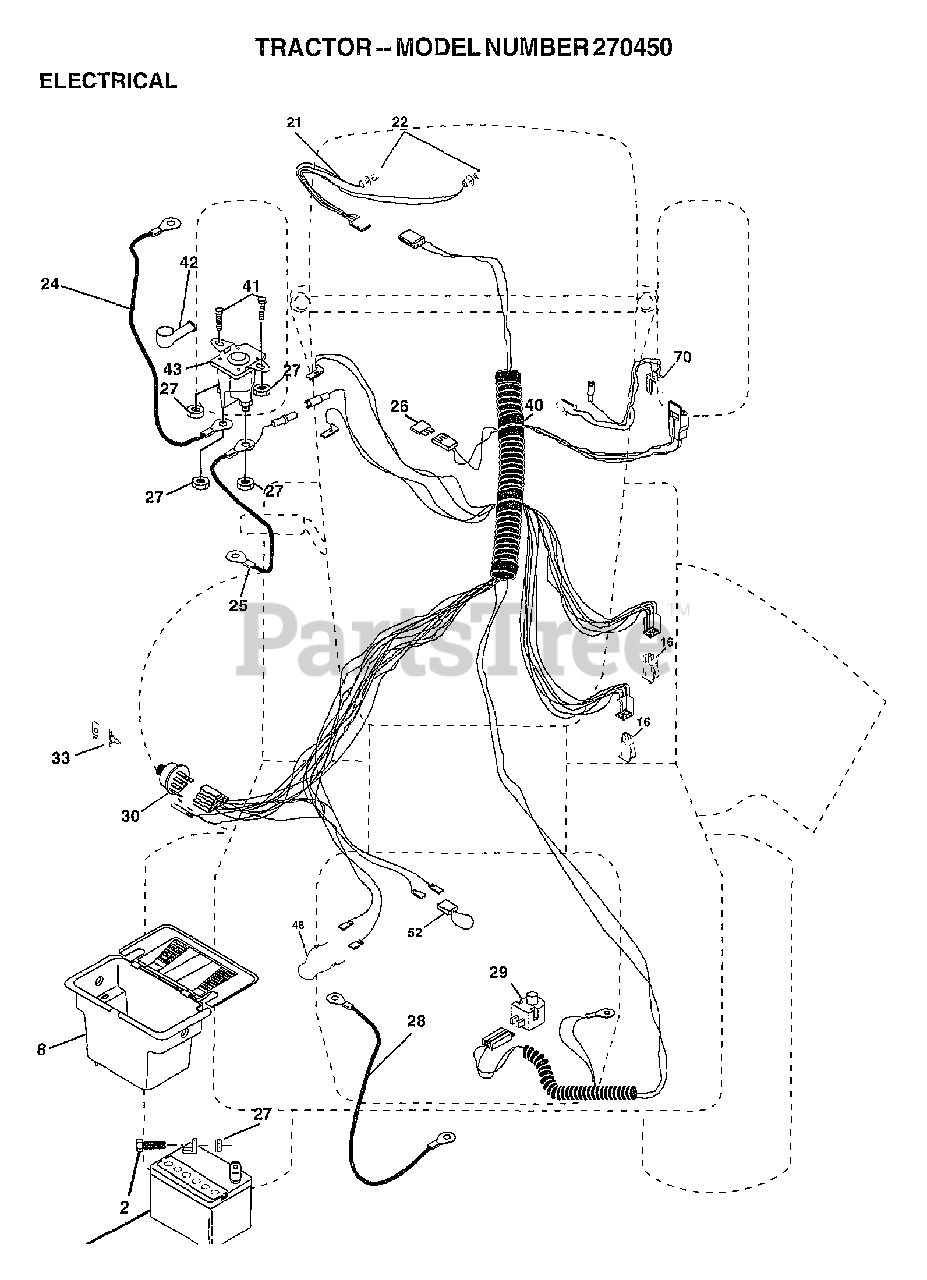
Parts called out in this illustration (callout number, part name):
2	BOLT LT
8	"CASE,BATTERY.MECH"
16	SWITCH INTERLOCK
21	HARNESS.ASM.LIGHT W/4152J
22	HEADLAMP BULB
24	"CABLE T, BATTERY"
25	CABLE.BTRY.6GA.RD
26	FUSE.15 AMP
27	NUT
28	CABLE T
29	SWITCH SEAT
30	SWITCH.IGN.
33	KEY MLD CRAF DELT
40	HARNESS IGN
41	BOLT HXHD FIN
48	ADAPTER AMMETER
52	PROTECTION LOOP
72	HARNESS ENG
